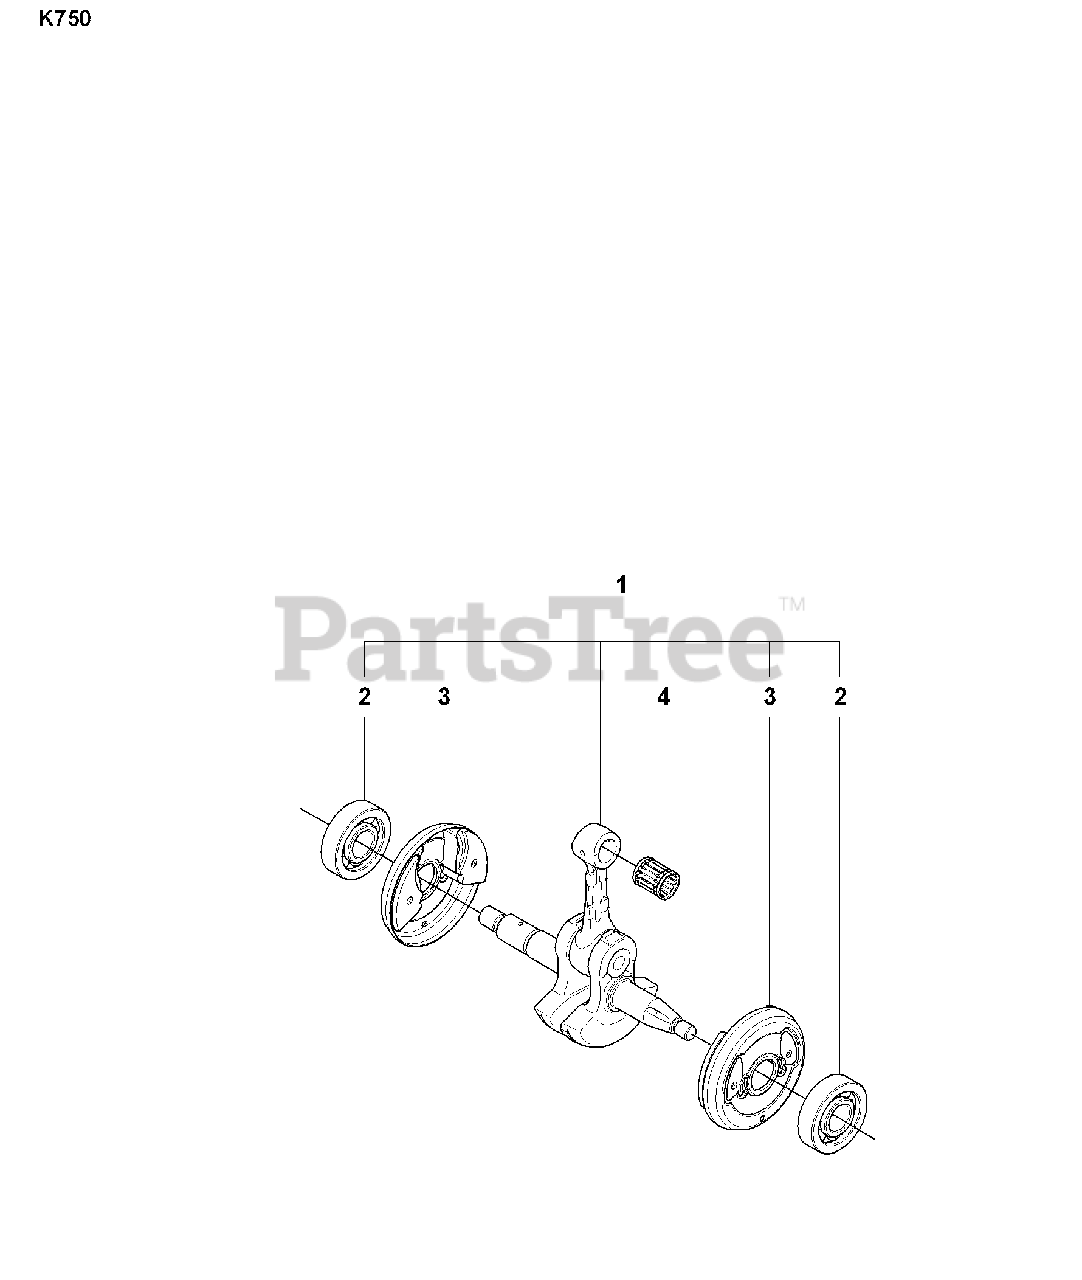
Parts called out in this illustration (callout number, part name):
1	CRANKSHAFT ASSY
2	BALL BEARING
4	NEEDLE BEARING
